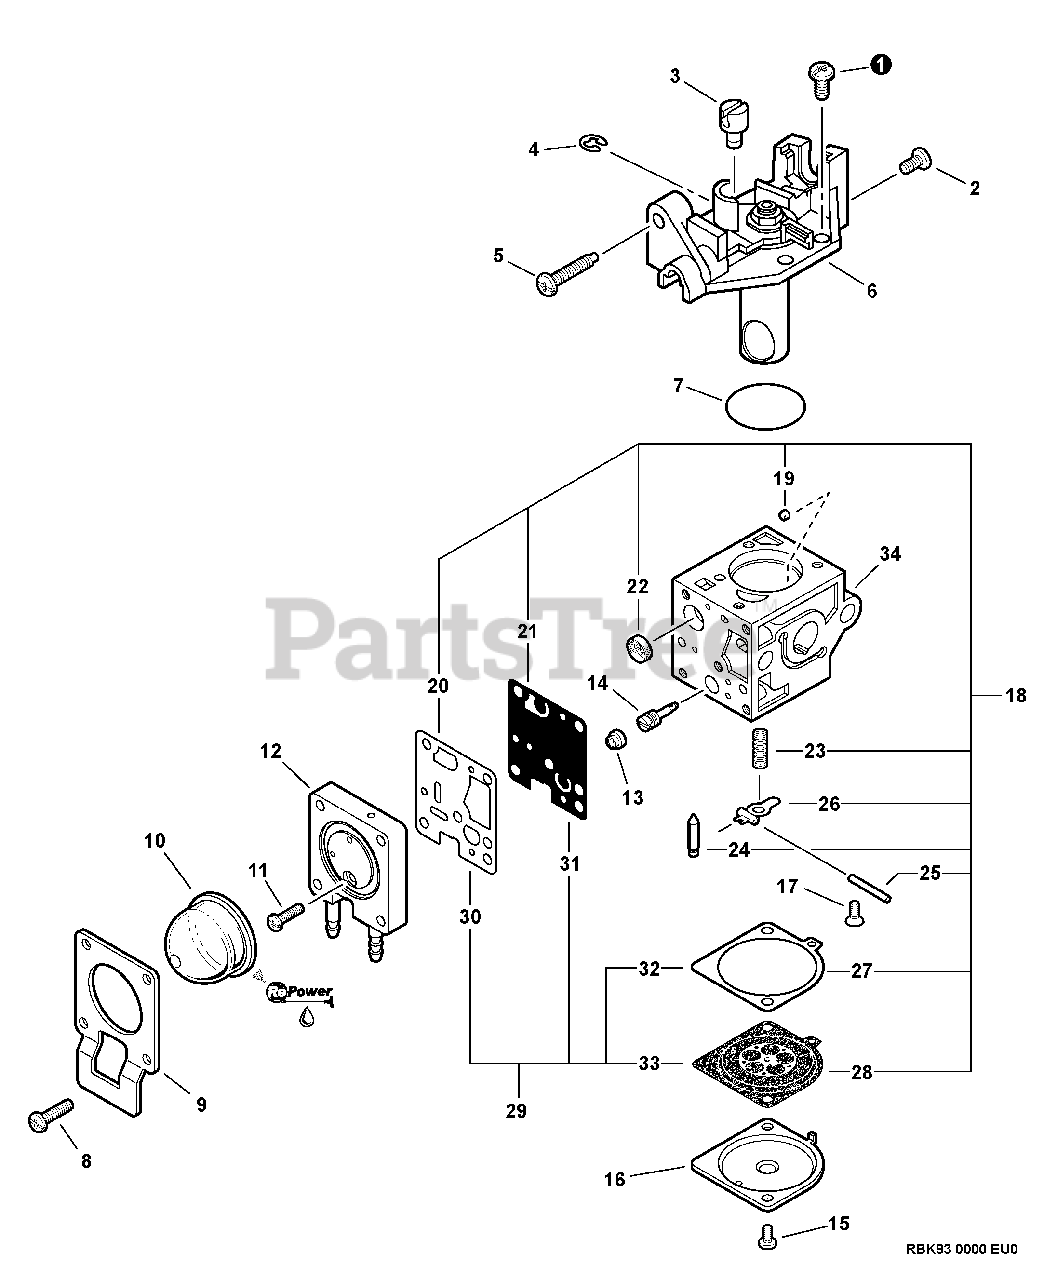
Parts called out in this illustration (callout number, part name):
4	RING, RETAINING
5	SCREW, IDLE ADJUST
6	ROTOR COVER ASSY
8	SCREW, RETAINER
9	RETAINER, PURGE BULB
10	BULB, PURGE
11	SCREW, PURGE BASE
12	BASE, PURGE
14	NEEDLE - HIGH SPEED
16	COVER, METERING
17	SCREW, METERING LEVER PIN
18	REPAIR KIT
19	GUIDE, ROLLER
20	GASKET, PUMP
21	DIAPHRAGM, PUMP
22	STRAINER
23	SPRING, METERING LEVER
24	VALVE, INLET NEEDLE
25	PIN, METERING LEVER
26	LEVER, METERING
27	DIAPHRAGM, METERING
28	GASKET, DIAPHRAGM
29	DIAPHRAGM/GASKET KIT
30	GASKET, PUMP
31	DIAPHRAGM, PUMP
32	DIAPHRAGM, METERING
33	GASKET, DIAPHRAGM
34	BODY, CARBURETOR
